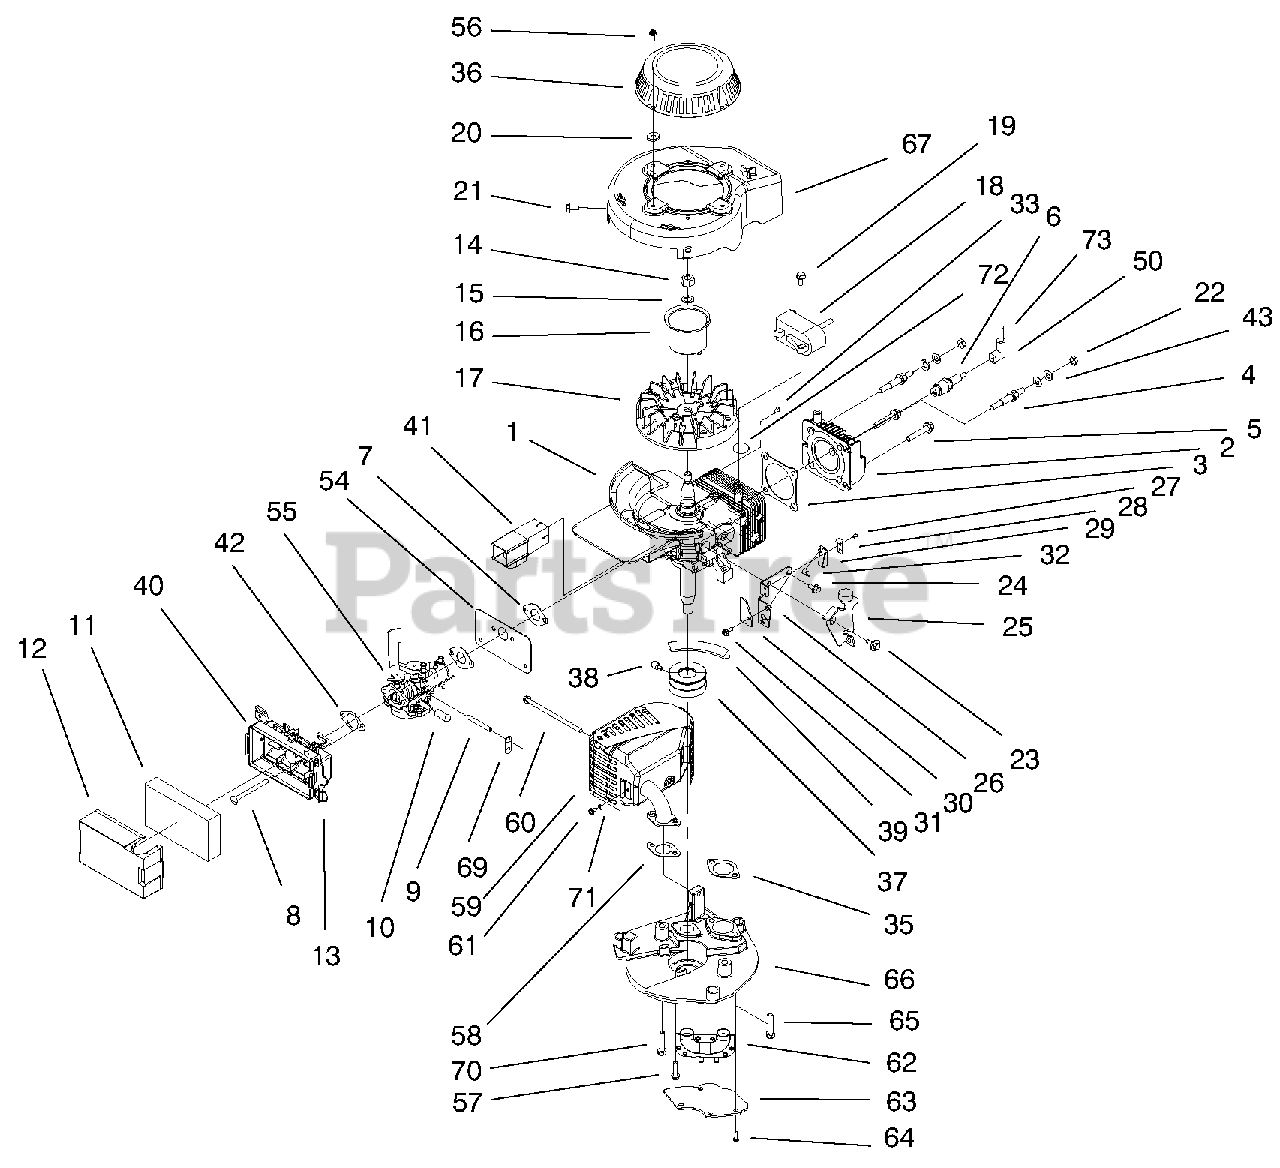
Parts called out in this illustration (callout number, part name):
1	Short Block ASM Service
3	Gasket-Head
6	Spark Plug
7	Intake Gasket
9	Primer Hose
11	Element-Air Filter
12	Cover-Air Filter
13	Retainer-Filter
15	Washer-Lock
16	Hub-Starter
17	Flywheel Machined Recoil
18	Ignition ASM
19	Screw-HWH
21	Screw
22	Nut-Lock
23	Shoulder Screw Brake
24	Screw (Brake)
25	ASM-Brake Plate
26	Plate-Mount Brake
27	Rivet-Self Expand Plas
28	Strap-Insulation
29	Strap-Ground
30	Stop-Ground Strap
31	Screw-Thread Forming
32	Brake Switch Lead Wire
35	Gasket-Exhaust
36	ASM-Starter
37	Pulley Engine
38	Screw-Set
40	Air Filter Base ASM
42	Gasket-Filter Base
43	Washer-Lock
50	Cover & Terminal
54	Heat Shield
55	Carburetor ASM w/Gasket
56	Screw-Sems
57	Screw-HWH
59	Muffler & Guard
62	Transfer Tube
63	Cover Plate
65	Screw-HH
66	Muffler Plate Machining
67	Shroud ASM
69	Retainer Hose
70	Screw-Hhd Washer
71	Washer-Lock
72	Tie Strap
73	High Tension Lead
